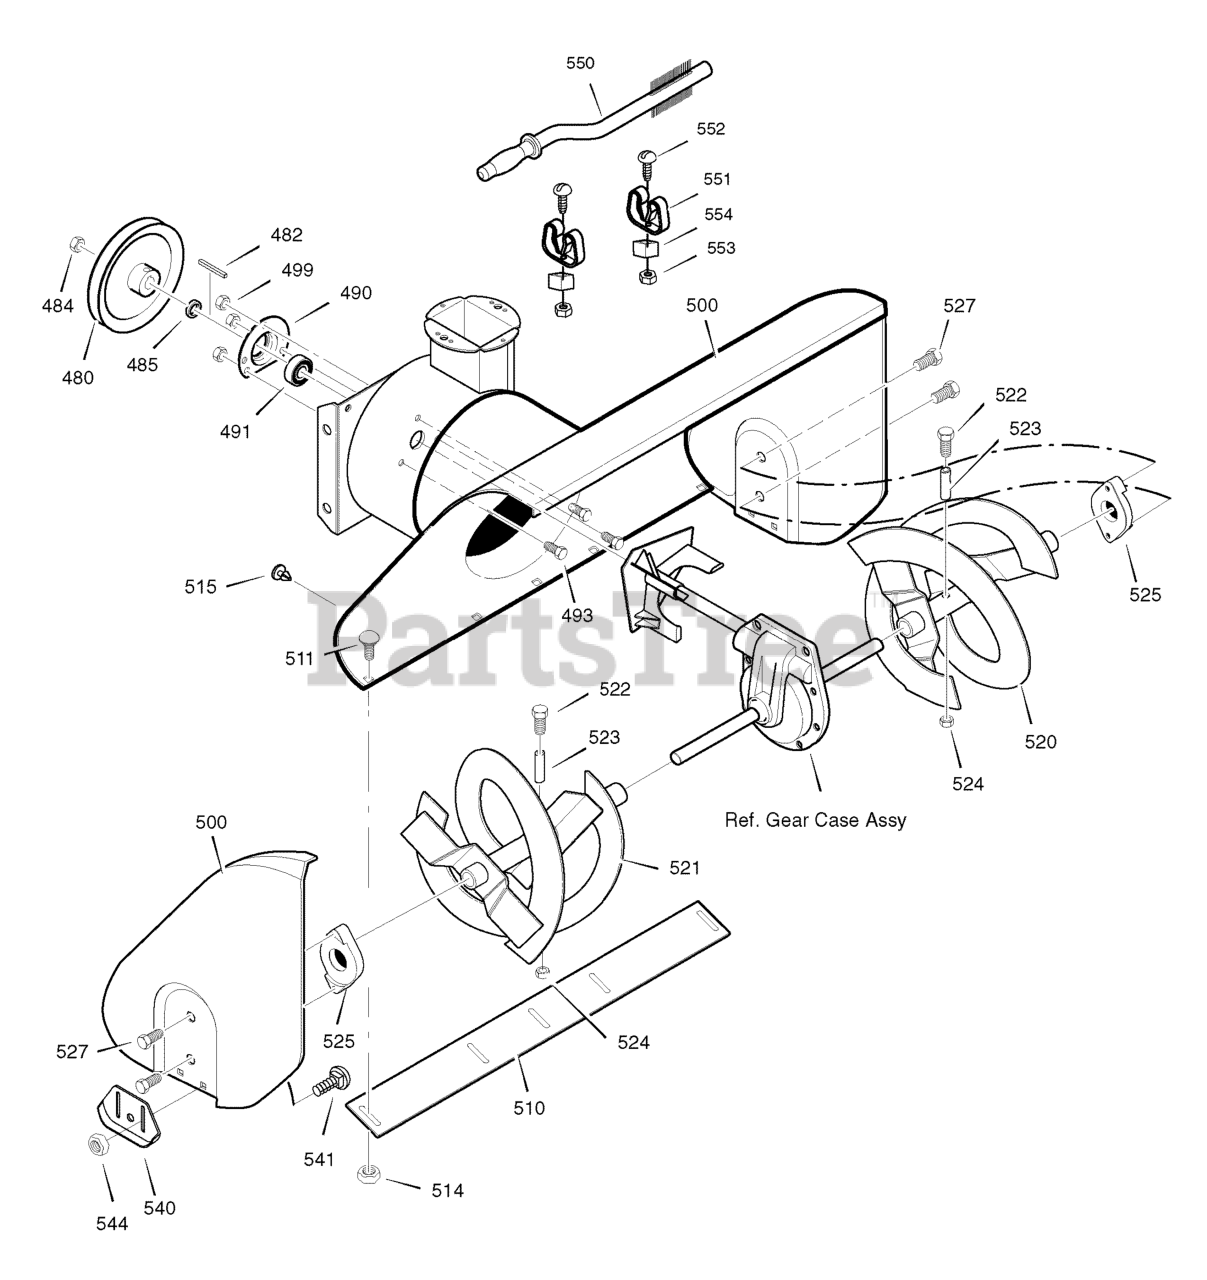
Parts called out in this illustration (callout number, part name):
480	PULLEY, 4L 8.40 OD.
482	KEY, SQUARE 3/16 X 3/4
484	NUT, .50-20 HEXWDFLLK
485	SPACER, FRICTION PULLEY
490	RETAINER, BALL BEARING
491	BEARING, BALL
493	BOLT, HEX 5/16-18 X .62
499	NUT, 5/16-18 HEXWDFLLK
500	HOUSING, ASSEMBLY
510	BLADE, SCRAPER
511	BOLT, 1/4-18 X .75
514	NUT, 5/16- 18
515	PLUG, PANEL
520	AUGER, ASSEMBLY, LH
521	AUGER, ASSEMBLY, RH
522	SCREW, 1/4-20 X 1.75
523	SPACER, SLEEVE
524	NUT, 1/4-20
525	BEARING, FLANGE
527	SCREW, 5/16-18 x 0.75
540	SKID, HEIGHT ADJUST
541	BOLT, 5/16-18 X .75
544	NUT, 5/16- 18
550	BRUSH, CLEANOUT
551	CLIP, RETAINER
552	SCREW
553	NUT
